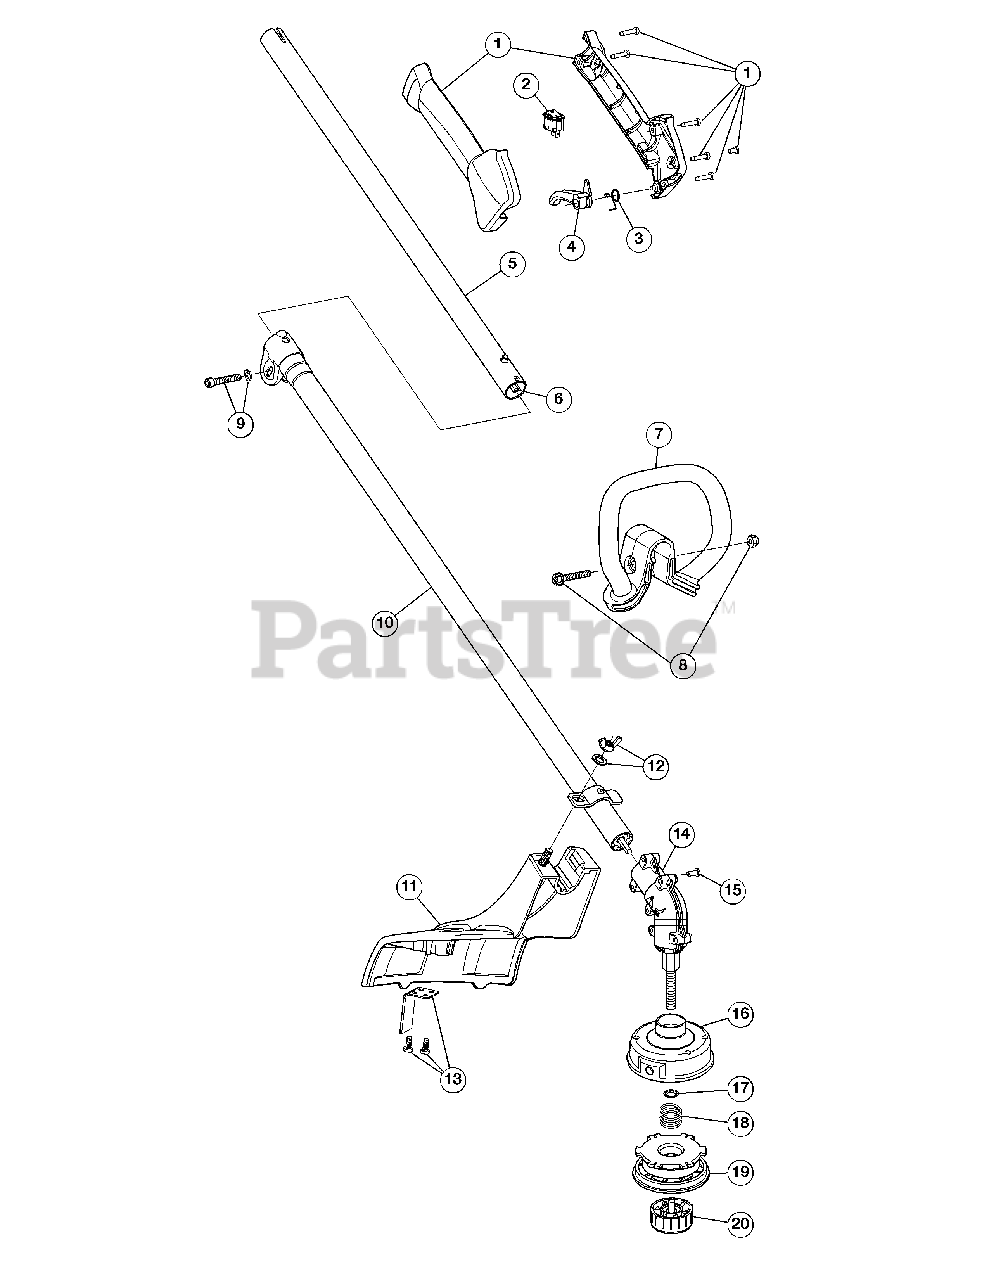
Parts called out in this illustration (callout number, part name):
1	Throttle Housing Assembly (Incl. 2 - 4)
2	Throttle Switch Assembly
3	Throttle Trigger Spring
4	Throttle Trigger
5	Upper Shaft Housing Assembly (Incl. 6)
6	Upper Flexible Drive Shaft
7	D-Handle (Incl. 8)
8	D-Handle Bolt
9	Clamp Hardware
10	Lower Shaft Housing Assembly
11	Shield Assembly (Incl. 12 & 13)
12	Shield Mounting Hardware
13	Blade Assembly
14	Gearbox Assembly (Incl. 15 - 20)
15	Anti-Rotation Screw
16	Outer Spool Assembly (Incl. 17)
17	Retainer
19	Inner Reel
20	Bump Head Knob Assembly
